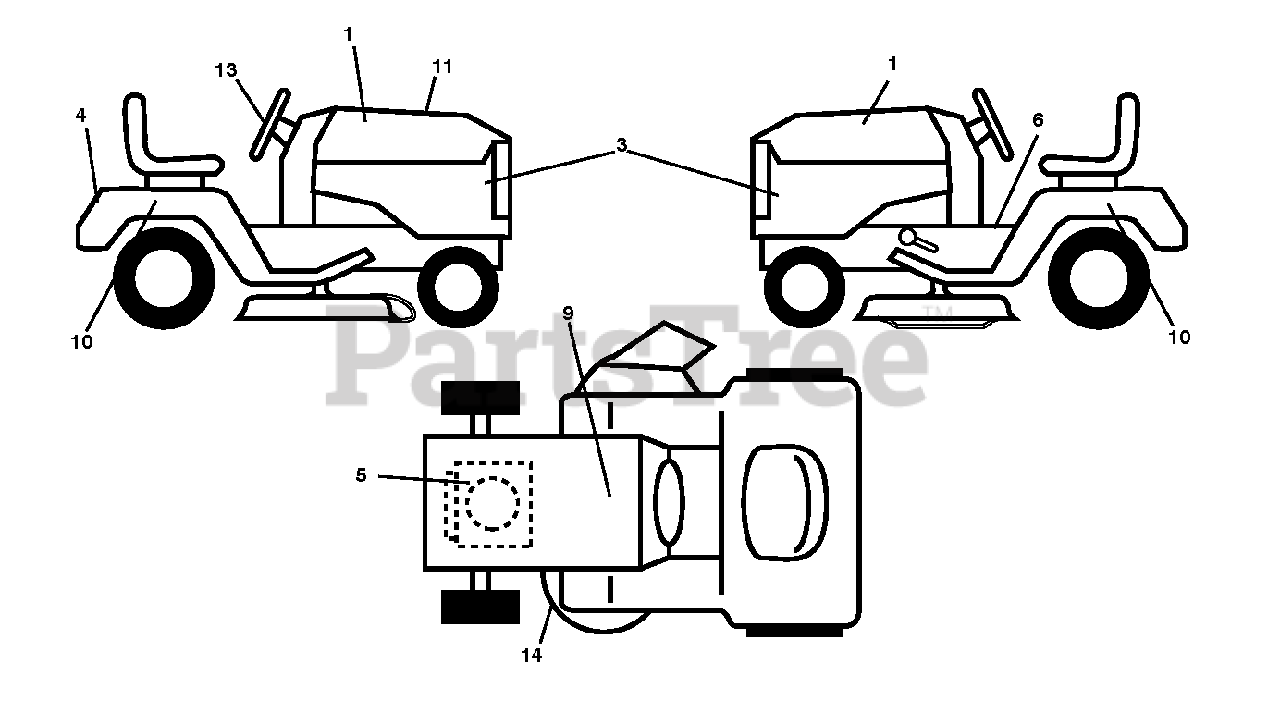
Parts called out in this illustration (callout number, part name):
4	DECAL.FEND.LOGO.POULAN.PRO
5	DECAL.ENG.BS.22.XRD.TWN.278445
6	Fender Warning Decal, English
9	DECAL BTRY SYMBOLS
10	DECAL.FEND.SD.SET.HYD.P-PRO
14	DECAL V BELT SCHEMATIC
14	PAD.FOOT.PEDAL.CONTRO
14	DECAL.BYPASS.FENDER.CRD.LT.YT
14	PAD, FOOTREST, LH
